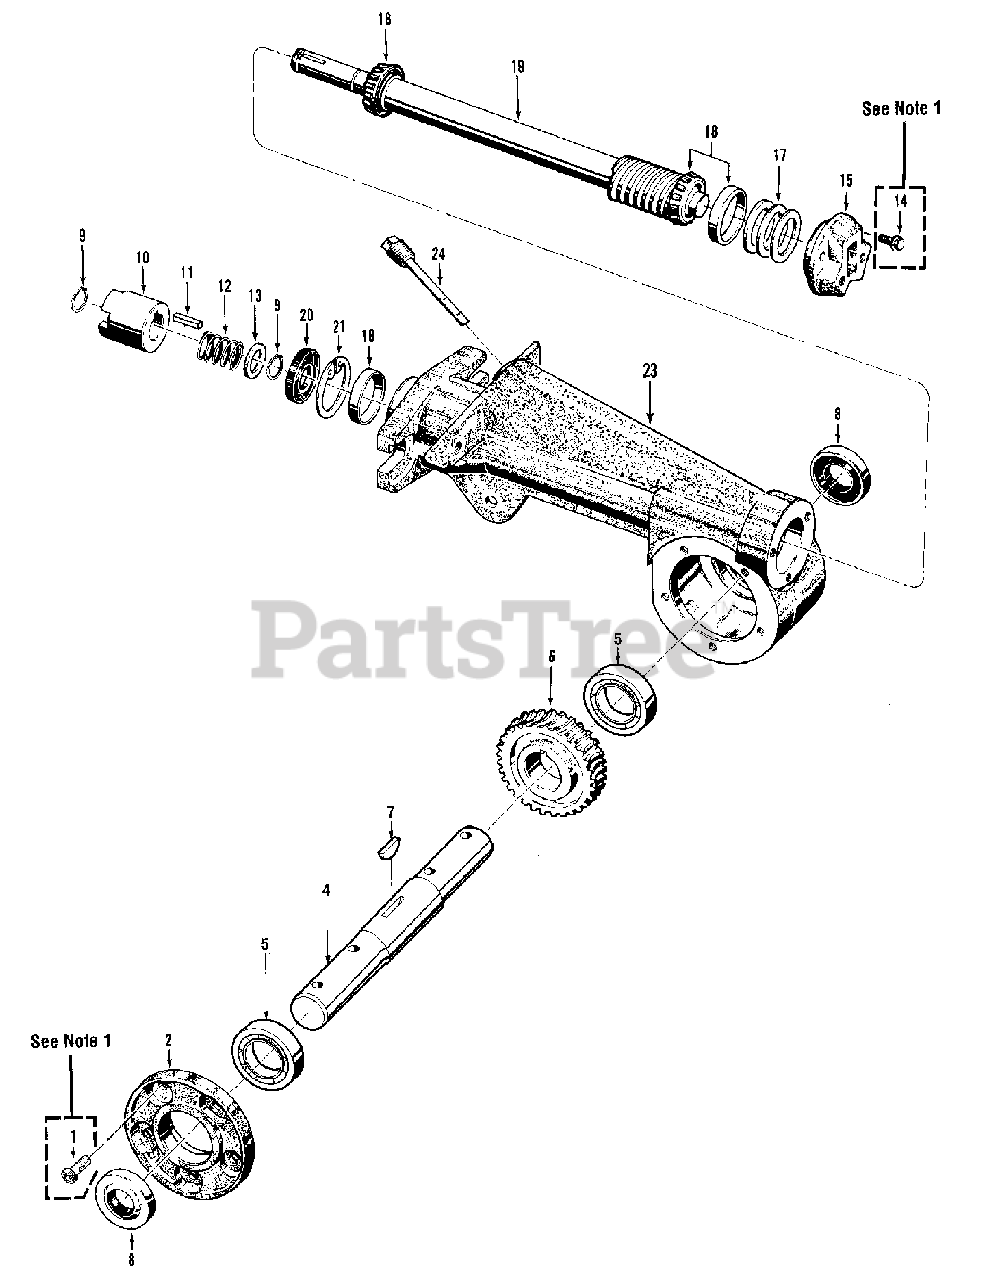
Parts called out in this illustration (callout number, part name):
1	Screw-self-sealing,1/4"-20
2	Cover-tiller housing
4	Shaft-tiller tine
5	Ball Bearing
6	Worm Gear-bronze, shaft
7	Key-tiller tine shaft, woodruff key
8	Seal-oil, tiller tine shaft
9	Retaining Ring-external
10	Dog Clutch-tiller drive shaft
11	Key-3/16" x 1"
12	Spring-dog clutch
13	Shim-dog clutch, 1/16"(.62") thick
14	Screw-self-sealing,1/4"-20 x 7/8
15	Cap-rear bearing
17	Shim-front bearing cap .010" thick
17	Shim-same as above, .030" thick
17	Shim-same as above,.005 thick
17	Shim-same as above, .062" thick
18	Bearing & Race
19	Shaft-main tiller drive
20	Seal-oil, drive shaft, front
21	Retaining Ring-internal
23	Housing-tiller attachment
24	Dipstick-oil, tiller attachment
